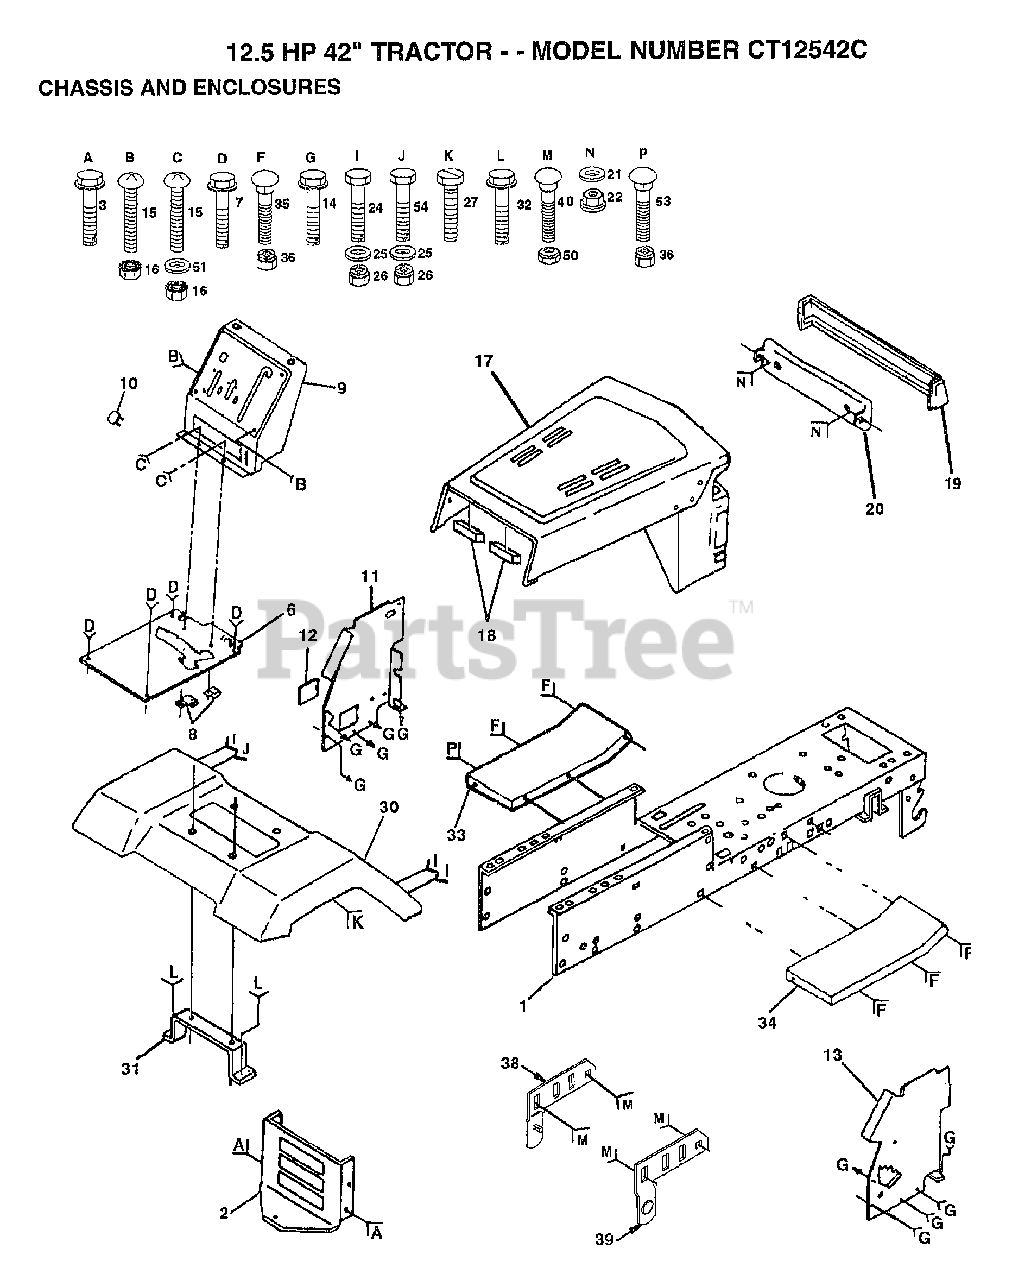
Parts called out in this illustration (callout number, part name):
3	SCREW
7	SCREW LT
8	CLIP T
10	PLUG BUTTON T
11	PANEL DASH LH
12	COVER ACCESS
14	SCREW LT
15	SCREW
17	HOOD/GRILL ASM
21	WASHER PM
22	PAL NUT LT
25	WASHER
27	SCREW LT
31	BRKT FENDER
32	SCREW
33	FOOTREST LH
34	FOOTREST
35	BOLT
38	PIVOT BRKT LH
39	PIVOT BRKT RH
40	BOLT
50	NUT
51	WASHER
